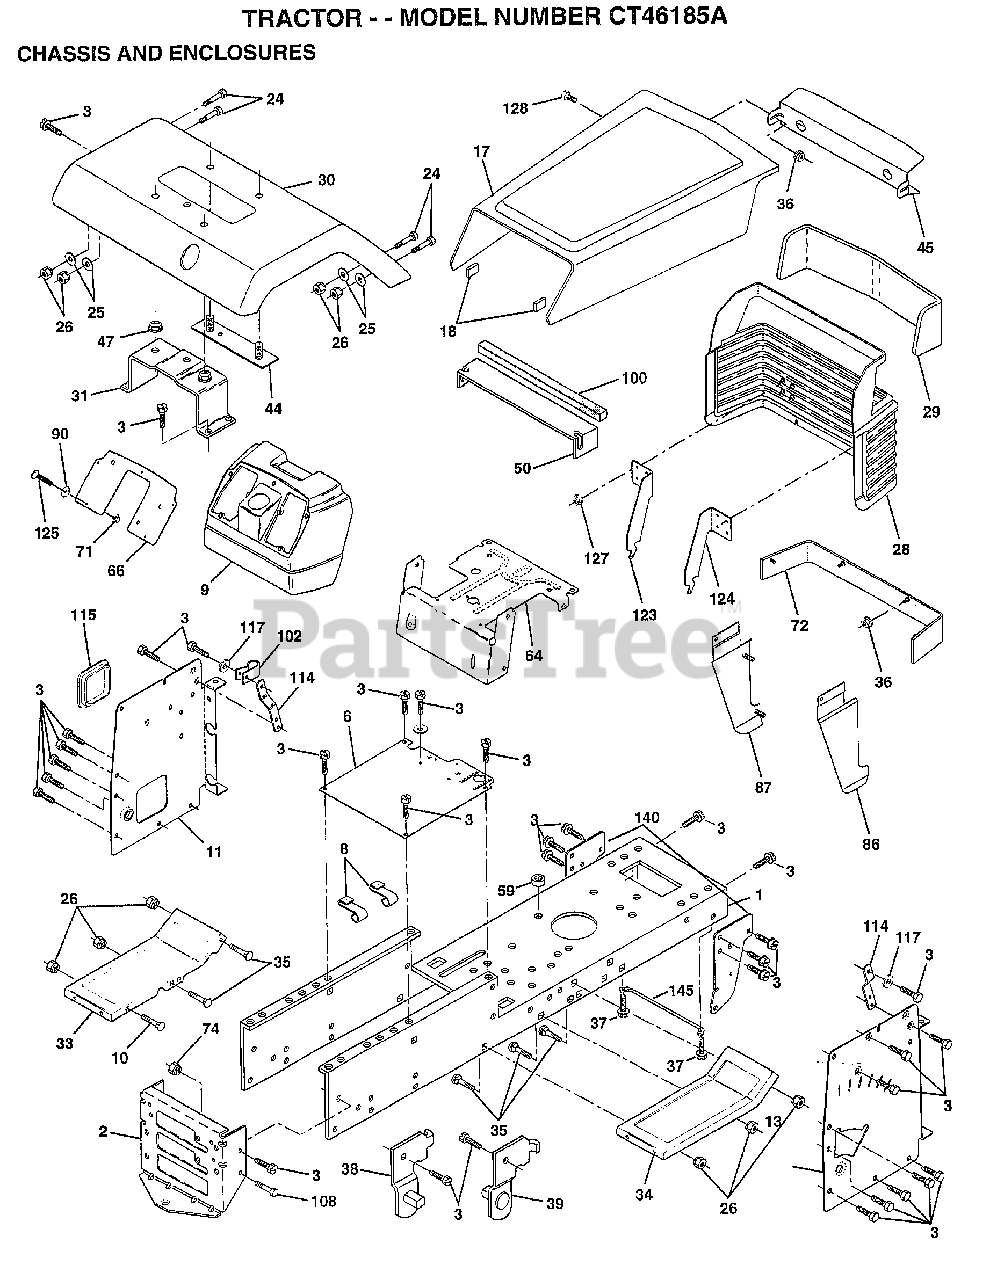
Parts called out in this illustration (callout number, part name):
3	SCREW
6	SADDLE
8	"CLIP,INSULATOR"
9	DASH.PLASTIC.BLK
11	DASHBRD.PANEL.LH
13	DASHBRD.PANEL.RH
17	HOOD/GRILLE ASM
24	BOLT
25	WASHER
26	NUT
28	GRILLE ASM WELD
30	FENDER PNT
31	BRKT.ASM.FENDER
33	FOOTREST.LH.LT/GT
34	FOOTREST.RH.LT/GT
35	BOLT
36	PAL NUT LT
37	SCREW LT
38	BRACKET ASM LH
39	BRACKET ASM RH
44	STRAP ASM FENDER
45	BEZEL.LIGHT.SLVR
47	NUT-PUSH YT
50	"BAFFLE,HOOD"
64	DASH.LOWER.LT
66	"PLATE-DASH,SILKSC"
72	STRAP FENDER ASM
86	PANEL SIDE RH ASM
87	PANEL SIDE LH ASM
90	WASHER PM
100	FOAM STRIP T
102	CLIP T
114	BRACKET.SUPT.DASH
115	COVER ACCESS
117	WASHER.SERRATED.
123	BRACKET.PICK.LH.
124	BRACKET.PICK.RH.
125	SCREW
127	PAL NUT
128	SCREW SPECIAL
140	BRKT SUSPENSION
145	"ROD POVOT,CHASSIS"
153	WASHER GT
